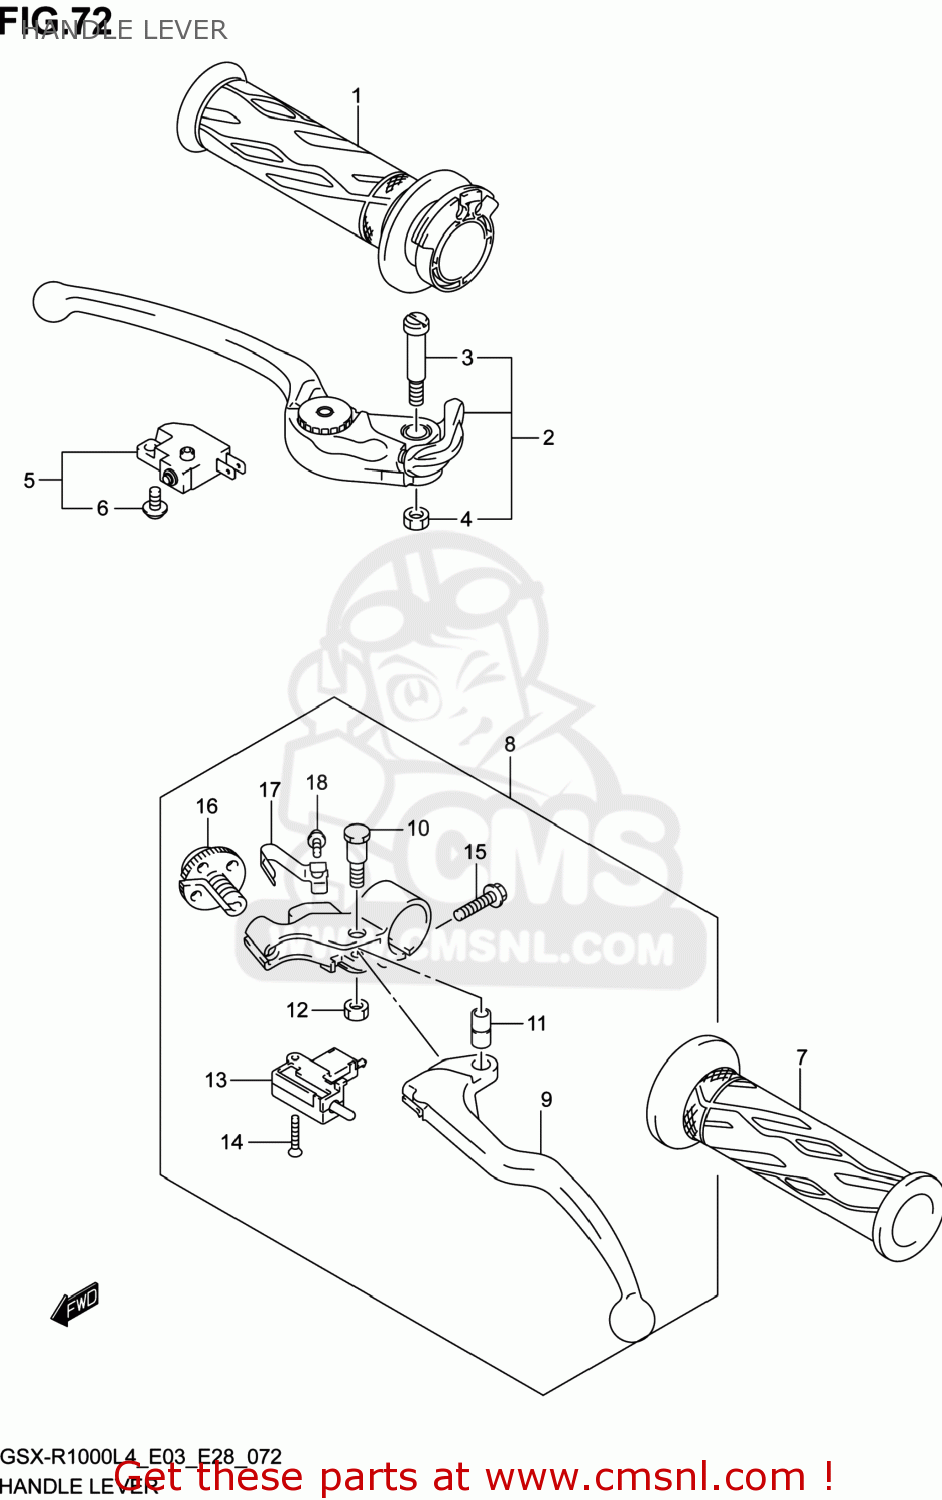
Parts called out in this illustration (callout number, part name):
1	GRIP,THROTTLE
2	LEVER ASSY,BRAKE
3	BOLT,LEVER PIVOT
4	NUT
5	SWITCH ASSY,FR BRAKE
6	SCREW
7	GRIP,L
8	LEVER ASSY,CLUTCH
9	LEVER,CLUTCH
10	BOLT,CLUTCH LEVER PIVOT
11	COLLAR
12	NUT
13	SWITCH,CLUTCH
14	SCREW
15	BOLT
16	NUT,ADJUSTER
17	SPRING,ADJUST
18	SCREW,SPRING
